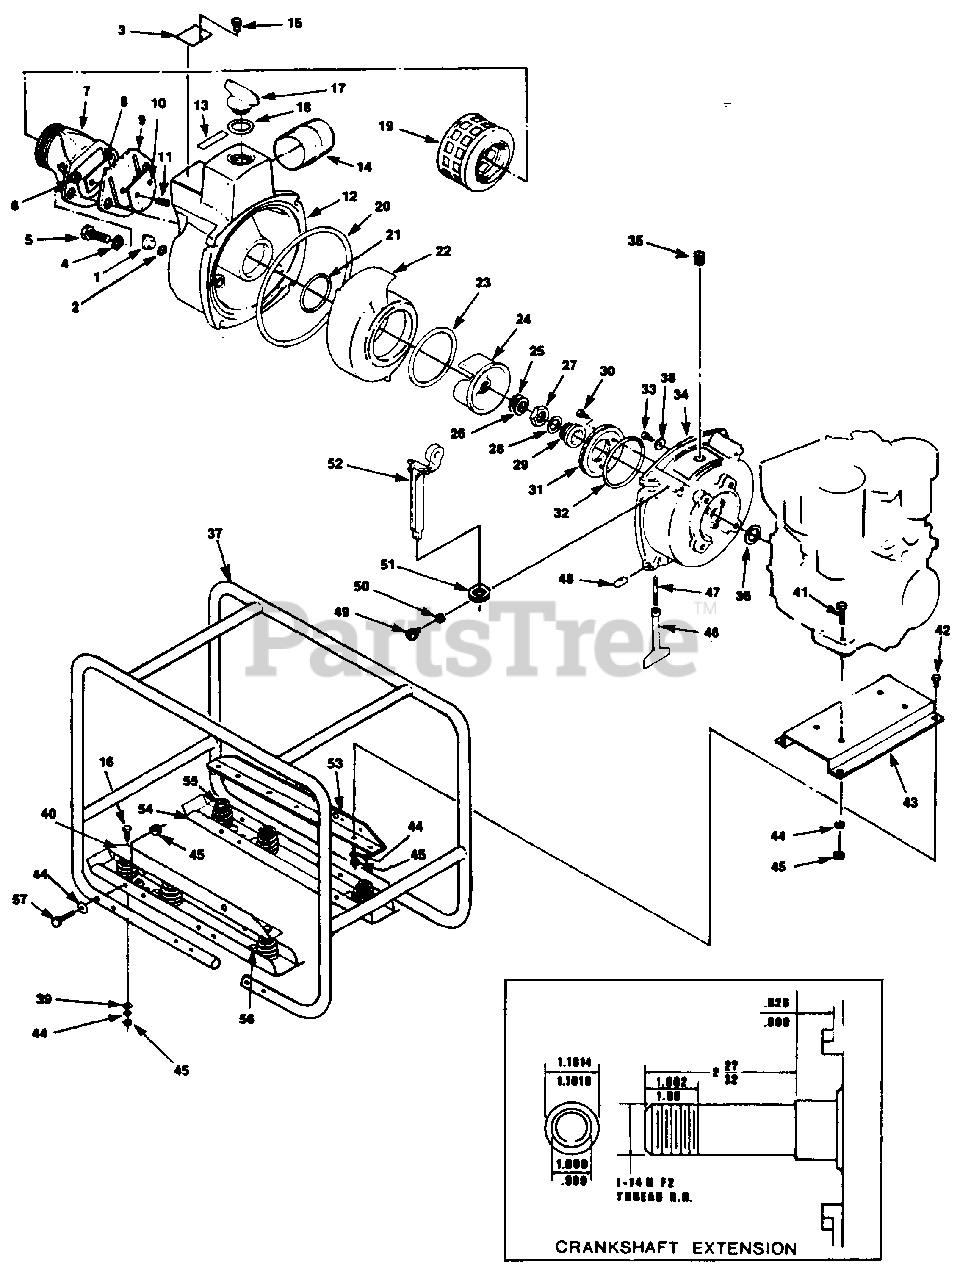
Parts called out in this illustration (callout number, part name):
1	PLUG- Drain
3	DECAL- Plate
4	WASHER- Lock 1/2"
5	SCREW- 1/2-13 x 1 1/4"
6	NUT- Hex 10-32
7	FITTING- Suction std. thread
8	PLATE- Small
10	PLATE- Large
11	SCREW- 10-32 x 1/2"
12	HOUSING- End
15	TACK- Metal
16	SCREW- Hex hd. 5/16-18 x 1"
17	PLUG- Wing
18	GASKET- Wing nut plug
19	STRAINER (1" openings)
20	GASKET- Pump body large
21	GASKET- End plate small
22	HOUSING- Impeller
23	GASKET- Impeller housing
24	IMPELLER
25	SHIM (.032") impeller
26	SHIM (.015") impeller
27	NUT- Impeller
28	SHIM- (.010") seal spring pressure
29	SEAL ASSEMBLY- Pump
30	SCREW- Hex hd. 1/4-20 x 5/8"
31	PLATE- Wear
32	"O" RING
33	SCREW- Hex hd. 3/8-16 x 1 1/4"
34	BODY- Pump
36	SLINGER
37	CAGE- Roll
38	WASHER- Sealing
39	WASHER- Flat 5/16"
40	ANGLE- Base (left)
41	SCREW- Hex hd. 5/16-18 x 2"
42	SCREW- Hex hd. 5/16-18 x 3/4"
43	BRACKET- Pump engine
44	WASHER
45	NUT-Hex 5/16-18
46	HANDLE- Disconnect
47	STUD- Handle
48	PIVOT- Handle
49	SCREW- Hex hd. 1/4-20 x 1/2"
50	WASHER- Flat 1/4"
51	BRACKET- Spanner wrench
52	WRENCH- Spanner
53	ANGLE- Base (right)
55	SPRING- Foot
